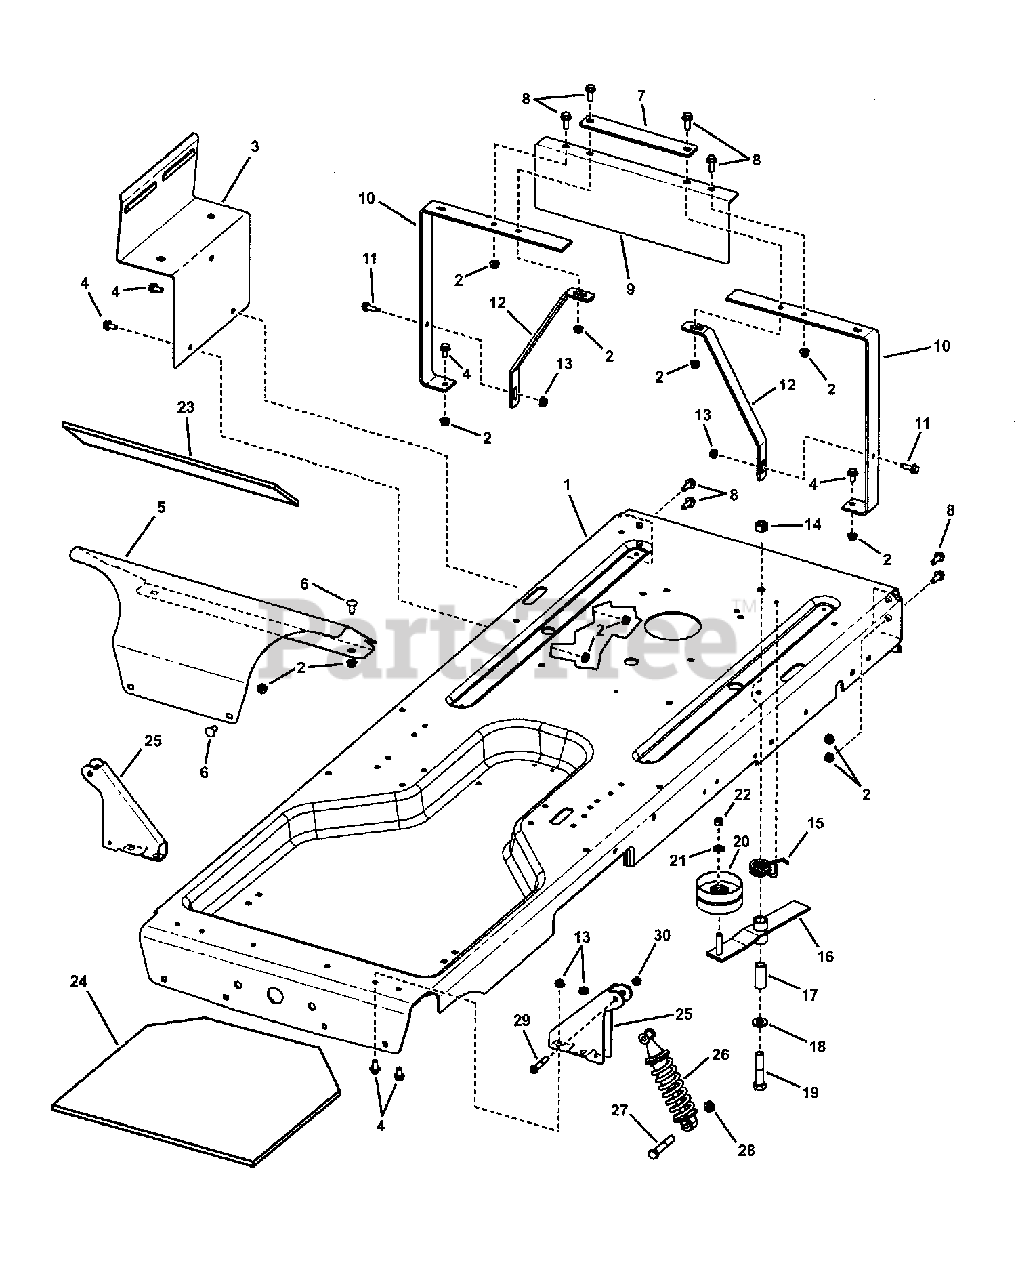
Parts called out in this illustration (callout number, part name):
1	FRAME, RZT, Simplicity Orange
2	NUT, Hex Flange Lock, 5/16C GR5 YZ
3	BRACKET, Tank
4	CAPSCREW, Hex Head, Whiz Lock, Flange, 5/16C X5/8 GR5 YZ
5	FOOTREST, Simplicity, Orange
6	CARRAIGE BOLT, 5/16C X3/4 GR5 YZ
7	PLATE, Rear Seat Guard
8	CAPSCREW, Hex Head, Whiz Lock, Flange, 5/16C X7/8 YZ
9	HEAT SHIELD
10	BRACKET, Body Support
11	CAPSCREW, Hex Head Flange Taptite, 5/16C X1
12	BRACE, Hood / Fender
13	NUT, Hex Flange Lock, 5/16C GR5 BZ
14	NUT, Hex Center Lock, 1/2C GR5 YZ
15	SPRING, Torsion, RH Wind
16	WELD, Hydro Idler
17	SPACER, Hydro Idler, Yellow
18	WASHER, YZ
19	CAPSCREW, Hex Head, 1/2C X2-1/2 GR5 BP
20	IDLER, 3.25OD X.391ID X1.63, Backside
21	WASHER, 3/8 SAE YZ
22	NUT, Hex Center Lock, 3/8C GR5 YZ
23	MAT, Foot Rest, RZT
24	MAT, Floor Pan
25	BRACKET, Shock
26	SHOCK ABSORBER
27	CAPSCREW, Hex Head, 7/16F X2-1/2 GR5 YZ
28	NUT, Hex Center Lock Jam, 7/16F GR5 YZ
29	CAPSCREW, Hex Head, 5/16C X1-3/4 GR5 YZ
30	NUT, Hex, Lock, 5/16C ESNA YZ
